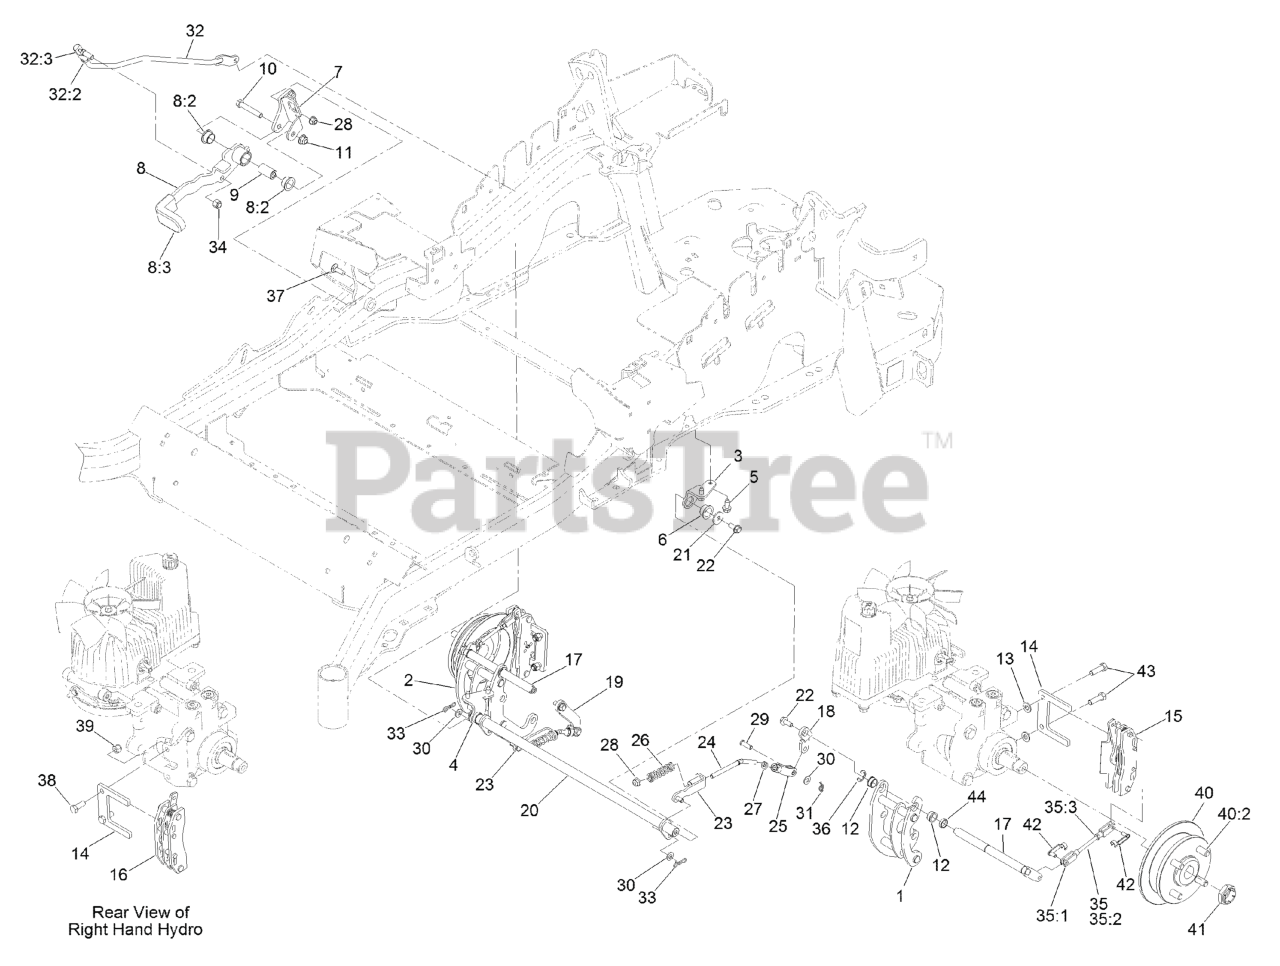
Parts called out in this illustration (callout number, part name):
1	MAINFRAME ASM
1:2	DECAL-DANGER
1:3	DECAL-WARNING
1:4	DECAL-HAZARD, PINCHED FINGER
1:5	DECAL-SPARK ARRESTER
2	PLATE,REAR GUARD
6	LH BUMPER ASM
6:2	DECAL-WARNING
7	BUMPER-RH
8	NUT-HF, NI
9	SCREW-CARR
10	SCREW-CARR
11	RH MOTION CONTROL COVER ASM
11:2	DECAL-CONTROL, MOTION
11:3	DECAL-PARK BRAKE, CE
12	LH MOTION CONTROL COVER ASM
12:2	DECAL-CONTROL, MOTION
13	GUARD-MUFFLER
14	DECAL-EXMARK LOGO
15	SCREW-HWH
18	DECAL-EXMARK LOGO
19	Decal-Patent Ttco.Com
20	NUT-PUSH
21	DECAL-FUEL FILL, CE
22	CUP-BEARING
